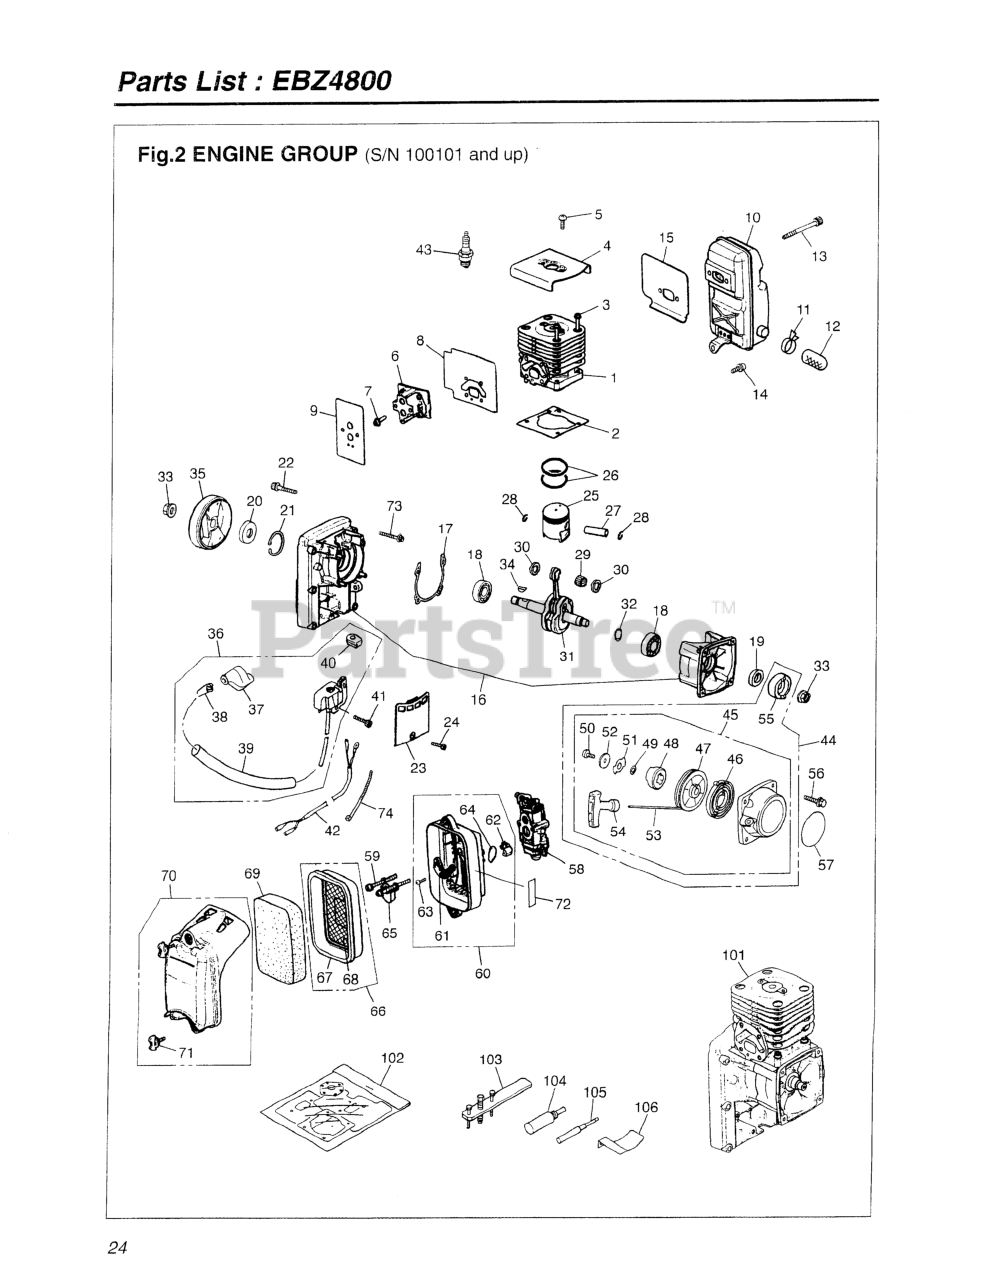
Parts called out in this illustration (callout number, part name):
1	CYLINDER
2	GASKET, BASE
3	BOLT
4	PLATE, CYLINDER
5	SCREW TORX
6	INSULATOR
7	BOLT (USE 848-815-2000)
8	848-GC0-14B1
9	GASKET, CARBURETOR
10	MUFFLER
11	ARRESTER
13	BOLT
14	BOLT
15	GASKET, MUFFLER
16	CRANKCASE COMP
17	GASKET, CASE
18	BEARING (REPLACES 2810-21240)
19	SEAL, OIL 15 X 25 X 7
20	SEAL (REPLACES 1400-21220)
21	RING, SNAP, M35 X 1.5
22	BOLT
23	COVER
25	PISTON
26	RING, PISTON (REPLACES -41210)
27	PIN, PISTON
28	RING, SNAP
29	BEARING
30	WASHER (RPLS 1491-41510)
31	CRANKSHAFT COMP
32	SHIM (REPLACES 848-870-G000)
33	NUT, M10
34	KEY
35	ROTOR
36	COIL ASSY.
37	CAP
38	SPRING
39	TUBE
40	GROMMET
41	BOLT TORX
42	CORD-C
43	SPARK PLUG (CMR7H)
44	STARTER ASSY (REPLACES -75000)
45	RECOIL ASSY (RPLS -75100)
46	SPRING (RPLS -75220)
48	DOG
49	WASHER
50	SCREW
51	RETAINER (RPLS 1861-75161)
52	WASHER
53	ROPE
54	KNOB
55	PULLEY (RPLS -75210)
56	SCREW TORX
57	LABEL, RECOIL (EBZ4800)
58	CARBURETOR (WYA 24A)
59	BOLT
60	BODY-A
61	PLATE,CHOKE
62	LEVER
64	RING,O
65	PLATE
66	PACKING-C
67	PACKING
69	ELEMENT
70	COVER-A
71	KNOB
72	LABLE,CHOKE
73	BOLT
101	SHORT BLOCK
102	GASKET KIT
103	PULLER ASSY
104	STOPPER (TOOL)
105	PULLER, PISTON PIN
